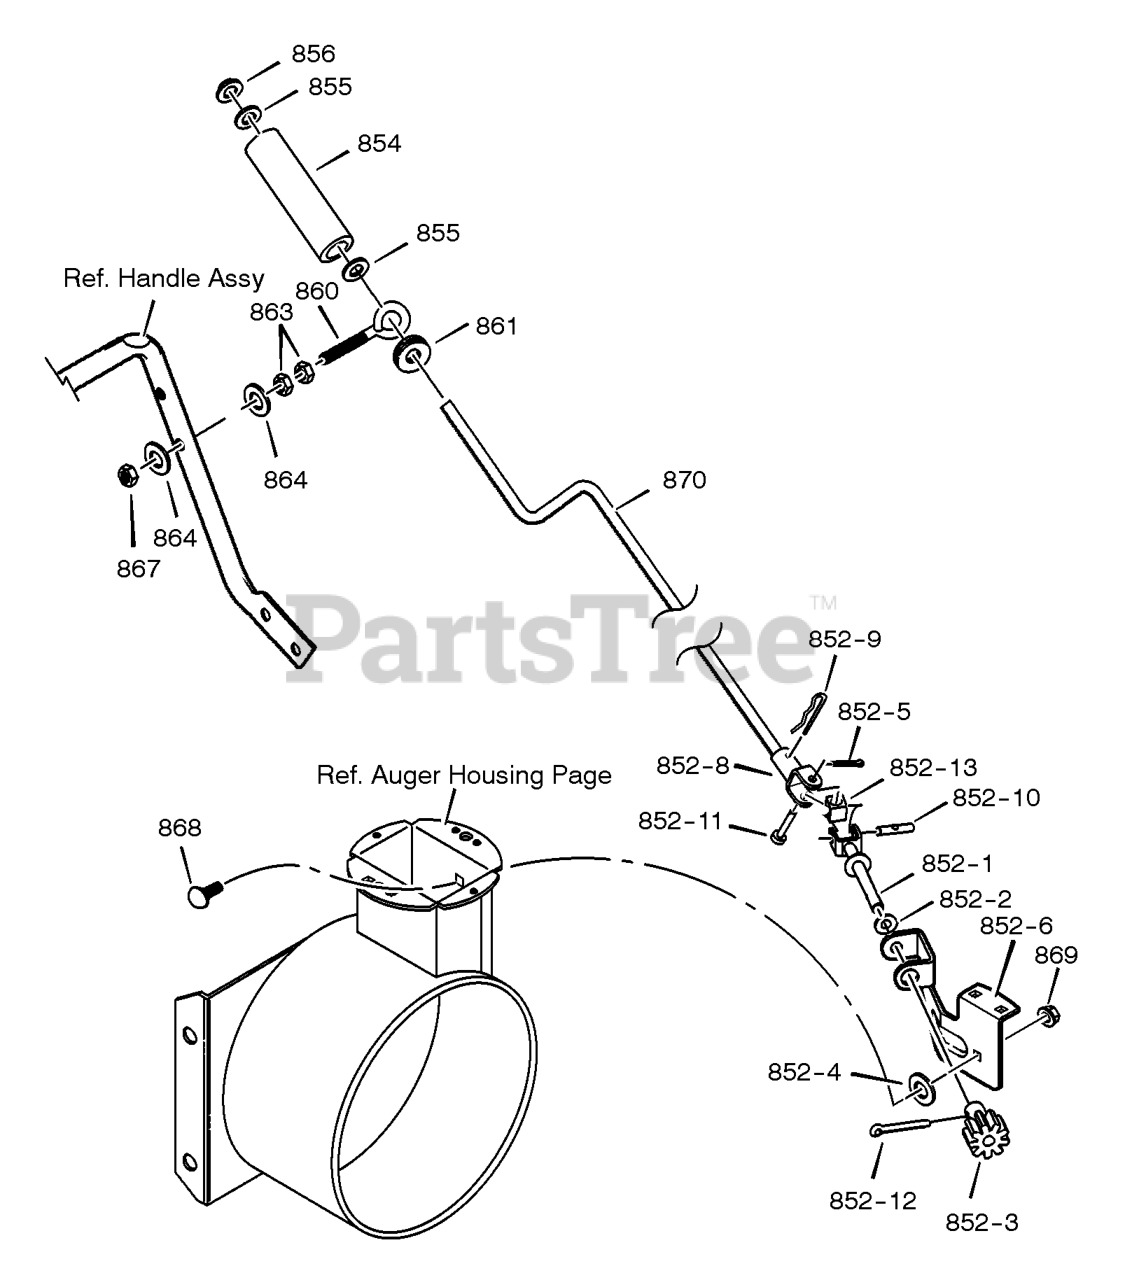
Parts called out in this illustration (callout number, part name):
852-1	ASSEMBLY, YOKE & ROD
852-2	WASHER, CURVED SPRING
852-3	GEAR, CHUTE ROTATION 9T
852-5	PIN, COTTER
852-6	BRACKET, GEAR MOUNT
852-7	PIN, COTTER
852-8	ASSEMBLY, YOKE ADAPTER YZ
852-9	PIN, HAIR
852-10	PIN, UNIVERSAL JOINT
852-11	PIN, CLEVIS
852-12	PIN, COTTER
852-13	HOUSING, UNIVERSAL
854	KNOB, SLEEVE
855	FLATWASHER
856	NUT, PUSH ON 3/8"
860	EYE BOLT 3/8-16X6.00
861	GROMMET, EYE BOLT
863	NUT, 3/8-16 HEXJAM
864	FLATWASHER .406X.81X.066
867	NUT, 3/8-16 HEXNYL
868	BOLT, CARRIAGE 1/4-20 X 1.00
870	CRANK, ASSY CHUTE
